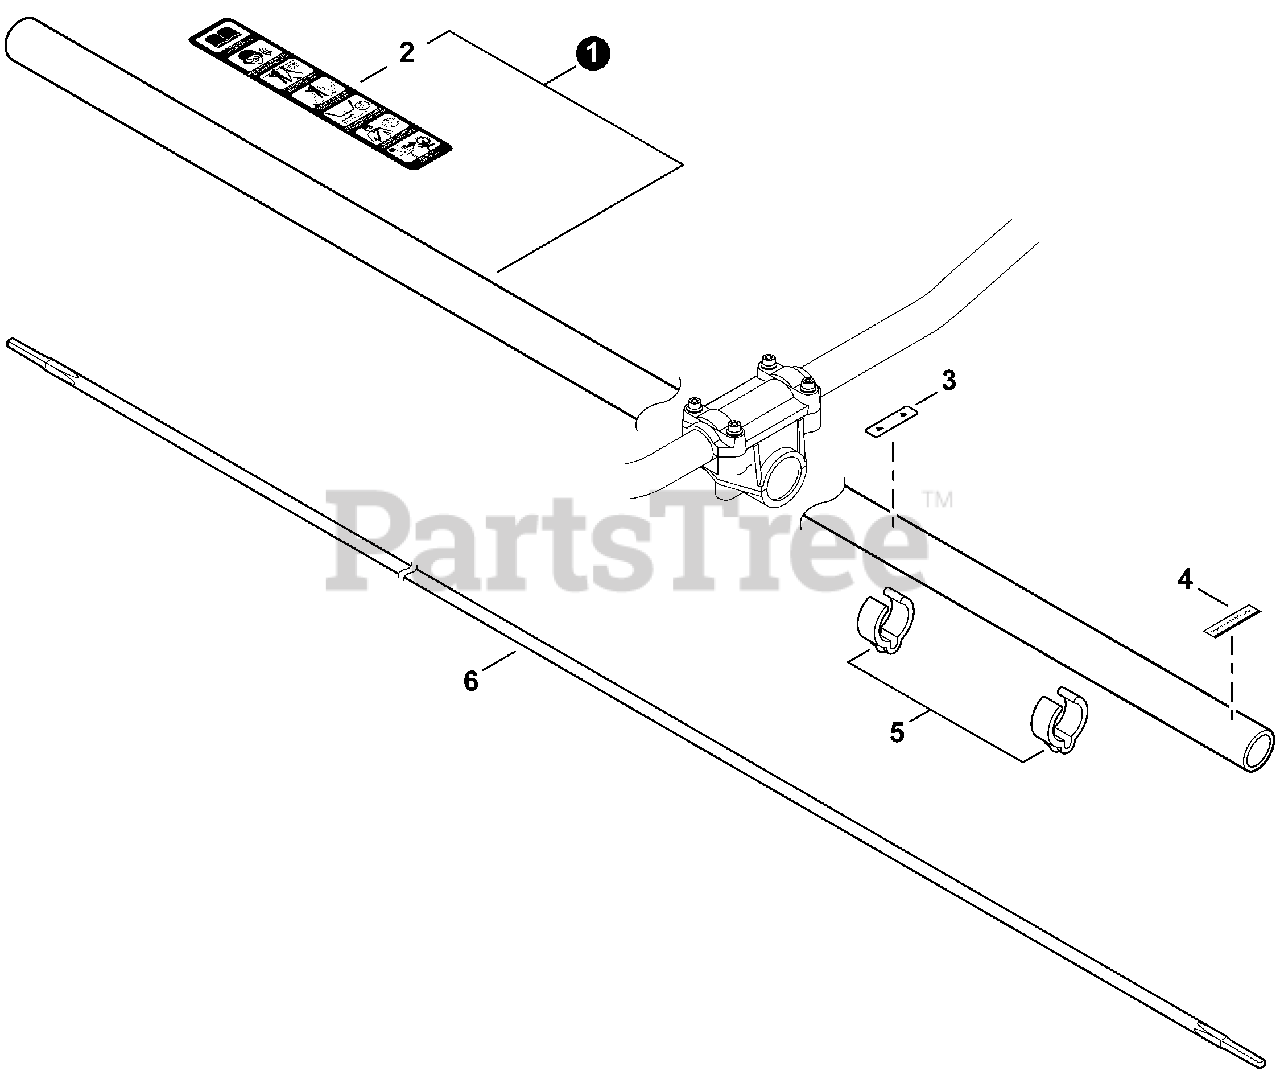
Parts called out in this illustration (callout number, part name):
1	MAIN PIPE ASSY
2	LABEL, CAUTION (BLADE CAPABLE)
3	LABEL - ALIGNMENT
4	LABEL - ALIGNMENT
5	CLIP, CABLE 25 MM
6	DRIVESHAFT
